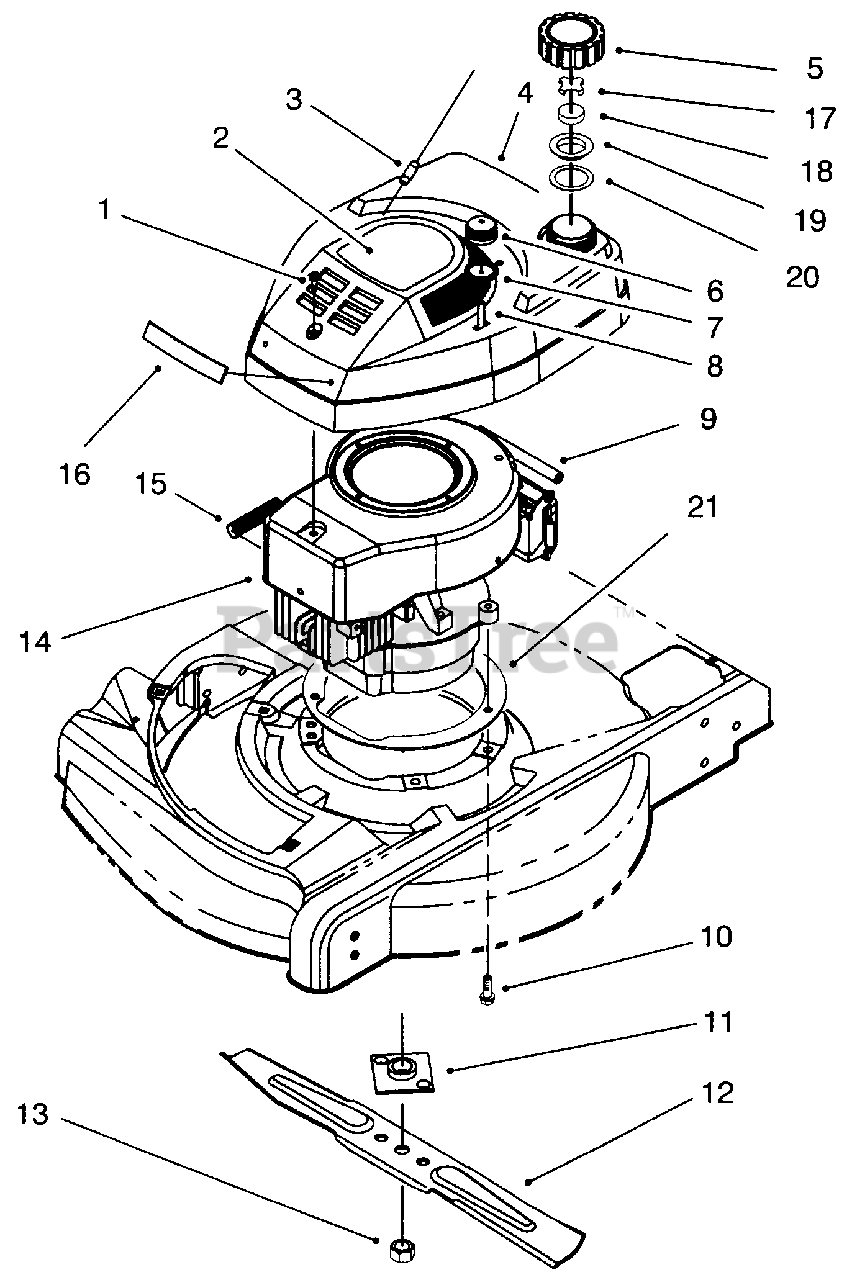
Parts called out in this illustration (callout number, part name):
1	Screw-Sems
2	Decal-Shroud
3	Rope-Stop
4	Tank & Shroud Assembly
5	Gas Cap Assembly (Incl. Ref. #17-20)
6	Bulb-Primer
7	Body-Primer
8	Hose-Primer
9	Line-Gas
10	Screw-Engine
11	Plate & Collar Assembly
12	Blade-21"
13	Nut-Blade
14	Engine
15	Spring-Compression
16	Applique-Shroud
18	Baffle-Foam
21	Plate-Engine
